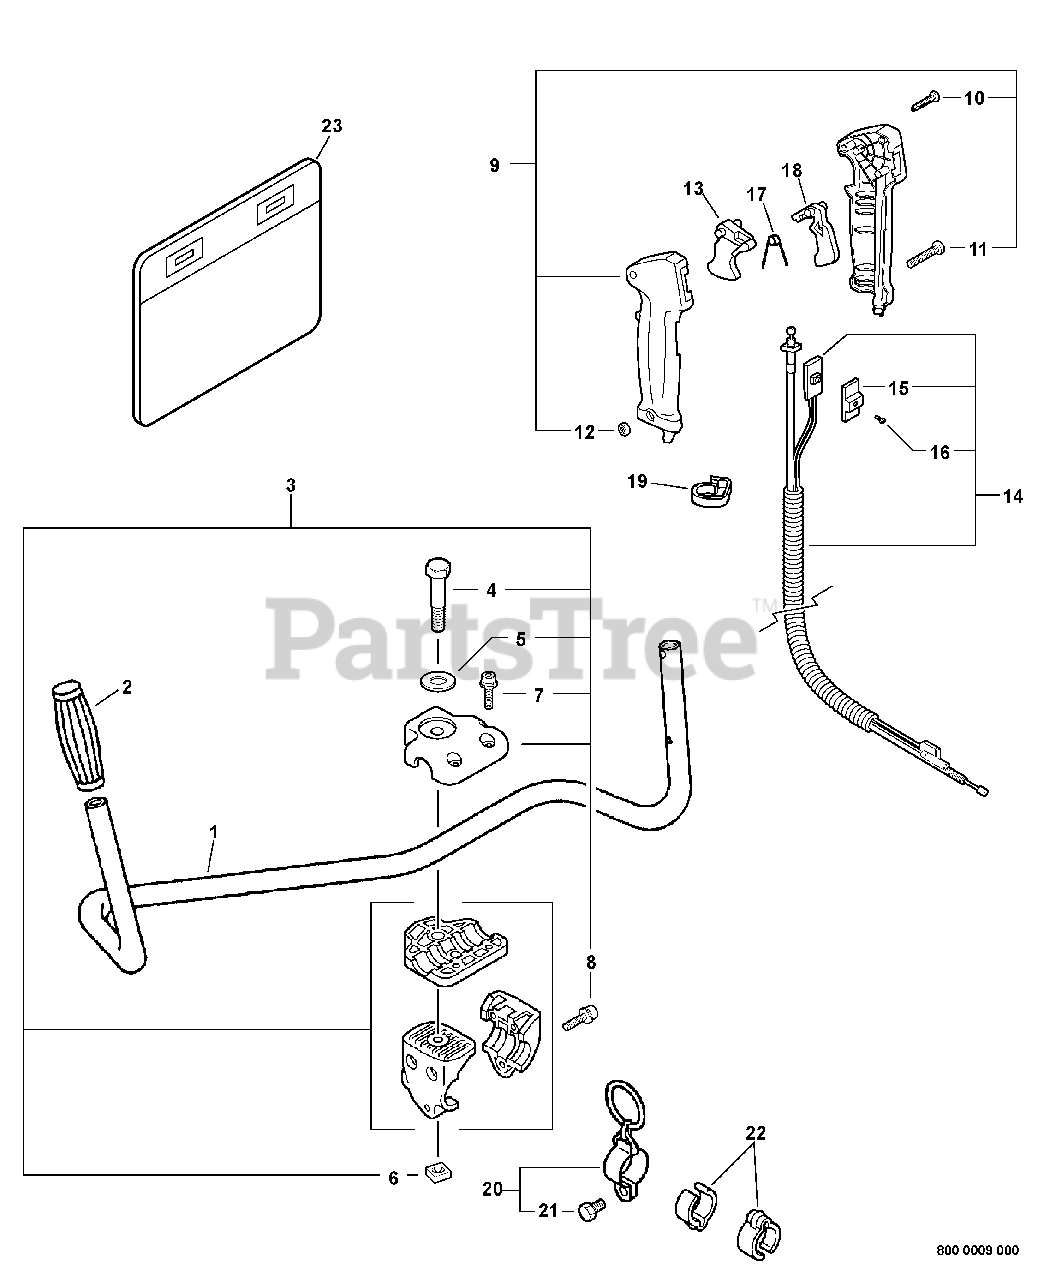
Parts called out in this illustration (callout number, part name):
1	HANDLE - FRONT
2	GRIP, HANDLE - LEFT
3	HANDLE BRACKET KIT
4	BOLT - 8X55
5	WASHER - 8
7	SCREW - 5X20
8	SCREW - 5X30
9	THROTTLE CONTROL ASSY
10	SCREW - 3X25
11	SCREW - 5X30
13	TRIGGER, THROTTLE
14	CONTROL CABLE ASSY
15	KNOB, SWITCH - ORANGE
16	SCREW - 3X10
17	SPRING, LOCKOUT LEVER
18	LOCKOUT, THROTTLE
20	HANGER KIT
21	BOLT - 5X12
23	CUSHION
